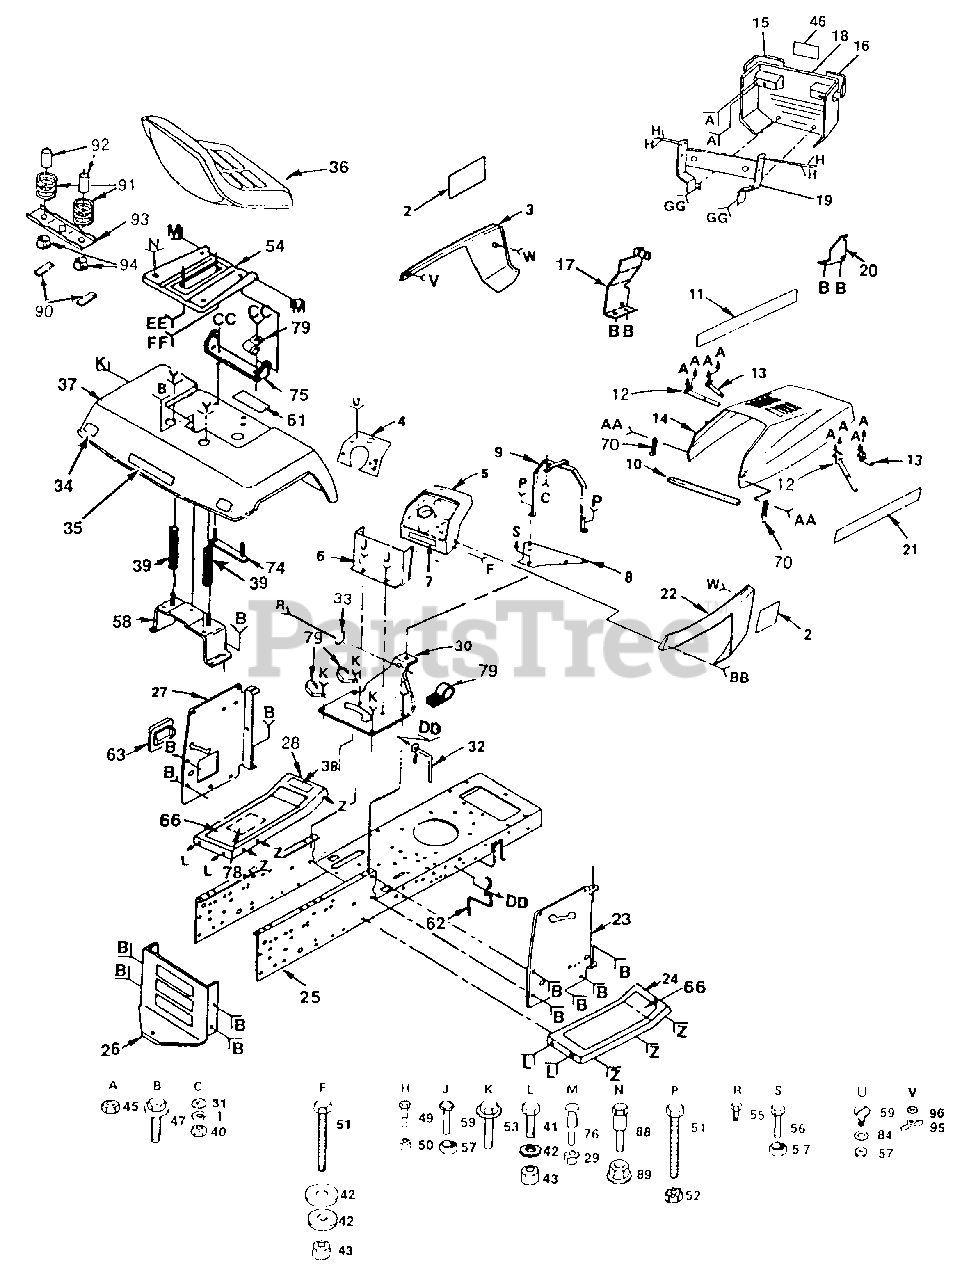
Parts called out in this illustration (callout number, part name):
1	Washer, Lock 1/4
2	Decal, Side Panel
3	Panel, Side L.H.
4	Plate, Dashboard
5	Dashboard
6	Dash, Lower
7	Decal, Instruction
8	Plate, Support, Battery
9	Support Assembly, Dash
10	Foam, Strip
11	Decal, Hood L.H.
12	Strap Assembly, Hinge, Rear
13	Strap Assembly, Hinge, Front
14	Hood
15	Lens, L.H.
16	Lens, R.H.
17	Bracket Assembly Frame Pivot L.H.
18	Grill Assembly
19	Support, Asm. Grill
20	Bracket Assembly Frame Pivot R.H.
21	Decal, Hood, R.H.
22	Panel, Side, R.H.
23	Panel, Dash, R.H.
24	Footrest, R .H.
26	Drawbar
27	Panel-Dash, L.H.
28	Footrest-L.H.
29	Nut-Crownlock 5/16-18
31	Washer 9/32 x 3/4 x 16 Ga.
32	Guide-Bell, Lower, Engine Pulley, L.H.
33	Bushing-Steering
34	Reflector-Taillight
35	Decal-Fender
36	Seat
38	Decal-Clutch/Brake
39	Spring, Seat
40	Nut-Hex 1/4-20
41	Bolt-Hex 3/8-16 x 3/4
42	Washer 13/32 x 13/16 x 12 Ga.
43	Nut-Crownlock 3/8-16
45	Nut, Hex, Keps 1/4-20
46	Decal, Grill, Husky
47	Screw-Hex Washer Hd. Thrd. Rolling 3/8-16 3/4 Type TT
49	Bolt-Shoulder 1/4-20
50	Nut-Crownlock 1/4-20
51	Bolt-Hex 3/8-16 x 1-1/4
52	Nut-Keps 3/8-16
53	Screw-Hex Washer Hd. Thrd. Forming 3/8-16 x 1/2 Type TT
55	Screw-Hex Head Self Tapping No. 10-16 x 1/2 Type B
56	Bolt-Hex 5/16-18 x 3/4 Gr. 5
57	Nut-Keps 5/16-18
58	Bracket Assembly - Fender
59	Screw-Truss Hd. 5/16-18 x 3/4
61	Decal-Caution
62	Guide-Belt, Lower, Engine, Pulley, R.H.
63	Cover-Access
66	Pad-Footrest
70	Latch-Hood
74	Strap Assembly-Fender
75	Bracket - Pivot, Seat
76	Bolt - Shoulder
78	Decal, Ground Drive.
79	Clip- Fuel Line
84	Washer 11/32 x 11/16 x 16 Ga.
88	Bolt Carriage 1/4 - 20 x 1-1/4
89	Nut - Hex Flange 1 /4 - 20
90	Foam Strip
93	Bracket - Switch Mount
94	Snap Bushing
95	Wing Nut 1/4 - 20
96	Washer, Lock 1/4 Ext/Int Tooth
